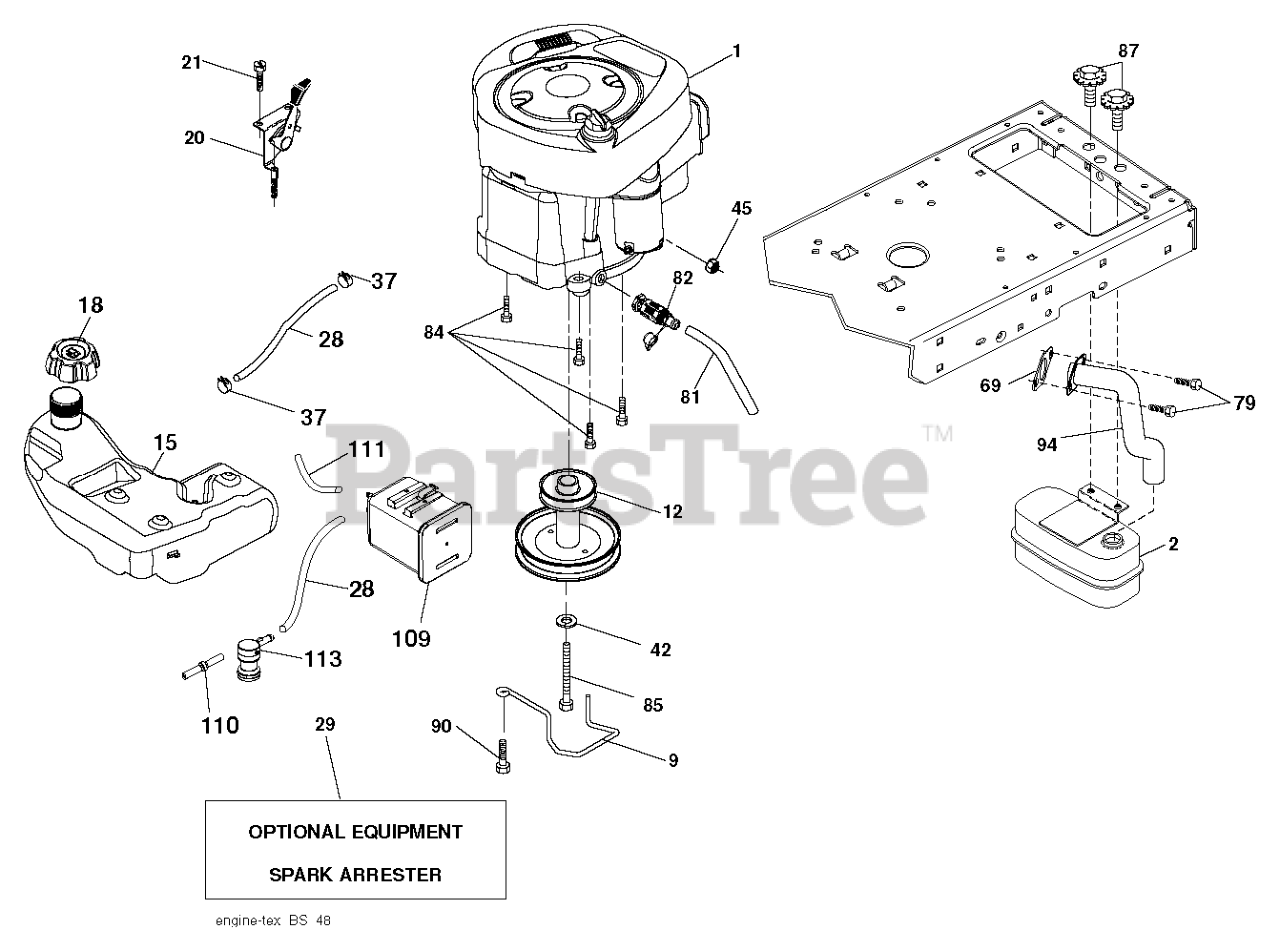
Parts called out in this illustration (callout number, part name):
2	MUFFLER.SINGLE.CYL.KOHL/B&S
9	KEEPER.BELT.ENGINE.4.2
12	PULLY ENGINE
15	TANK.ASM.FUEL.3GA.CARB
18	RP CAP ASM
20	CONTROL.TH/CK.COBRA.KO
21	SCREW.#10 X 0.750.BOS
28	LINE.FUEL.64"REAR.EMIS
29	KIT.SPARK ARRESTOR 794945 B&S
37	HOSE CLAMP
42	LOCKWASHER
45	NUT
69	REPL BY 532 27 22-93
79	SCREW.SOCKET HD.5/16-1
81	TUBE, DRAIN OIL ASM.
82	VALUE.OIL.DRAIN
84	SCREW.3/8-16
85	BOLT HEX 7/16-20X4-1/4"
87	BOLT.5/16-18UNCX3/4 W/SEMS.BLK
90	SCREW 3/8-16X1
94	EXHAUST.TUBE.B&S.
109	CANNISTER, CARBON
110	VALVE.ASM.ANTI-SLOSH
111	RP PURGE LINE
113	VALVE.SLANT.CARTRDG.90 DEG.TEX
